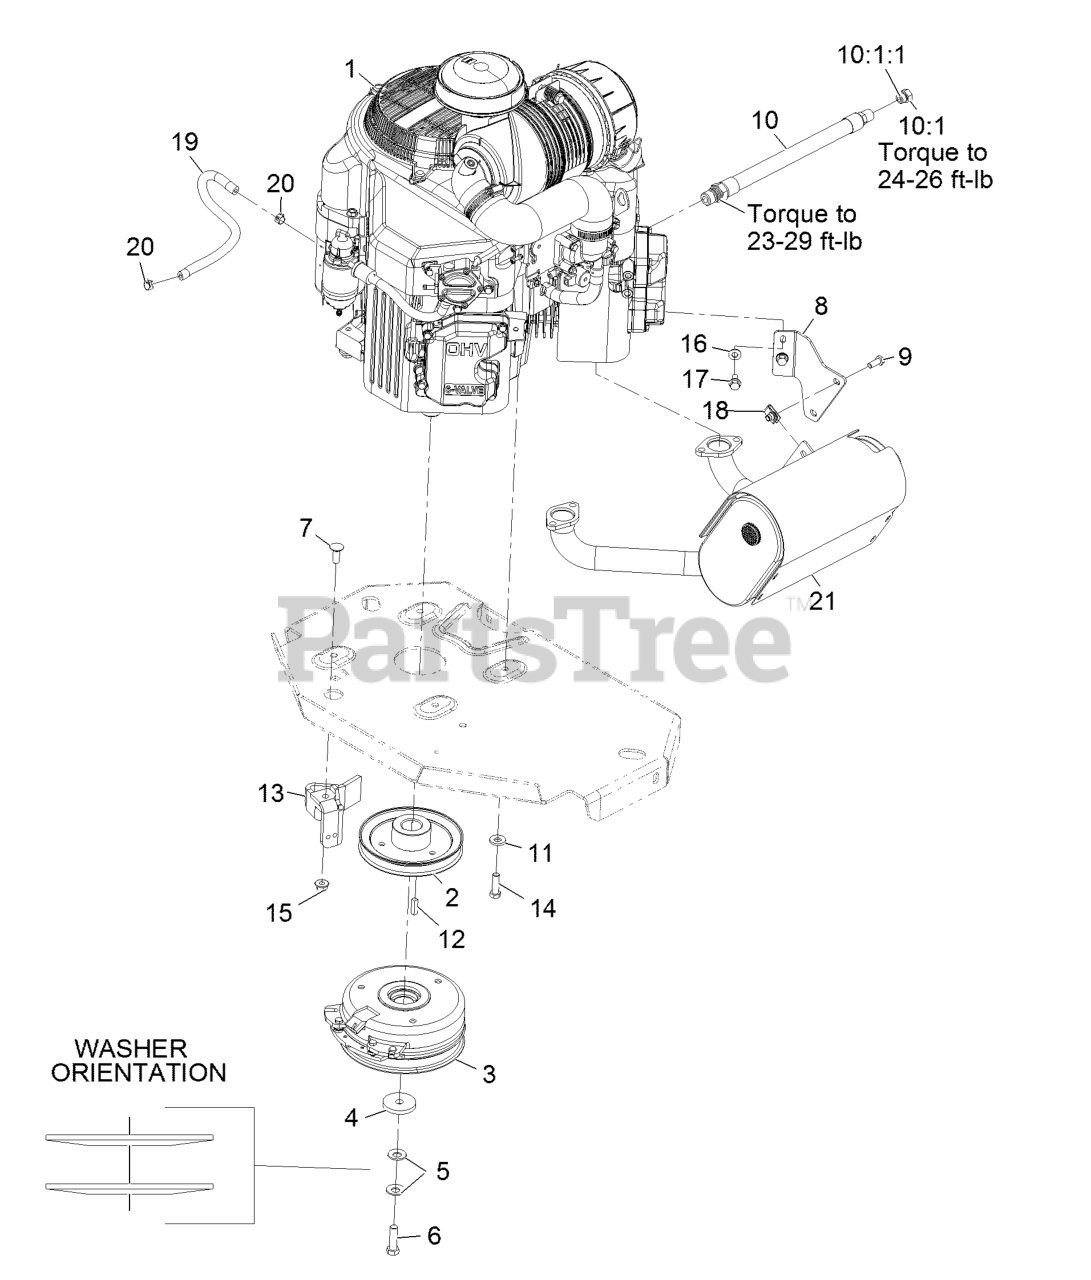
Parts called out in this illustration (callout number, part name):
2	SHEAVE
4	WASHER-CLUTCH
5	WASHER-SPRING
6	SCREW-HH 7/16-20 X 1 1/2 W/LOCTITE
7	SCREW-CARR
8	BRACKET-MUFFLER
9	SCREW-HH
10	ENGINE OIL DRAIN HOSE ASM
10:1	PLUG-HH
10:1:1	O-RING
11	WASHER-BELLEVILLE
13	CLUTCH-ANCHOR
14	SCREW-HH
15	NUT-HF, NI
16	WASHER-SPRING
17	SCREW-HHF
19	HOSE-FUEL
20	CLAMP-HOSE
21	MUFFLER
